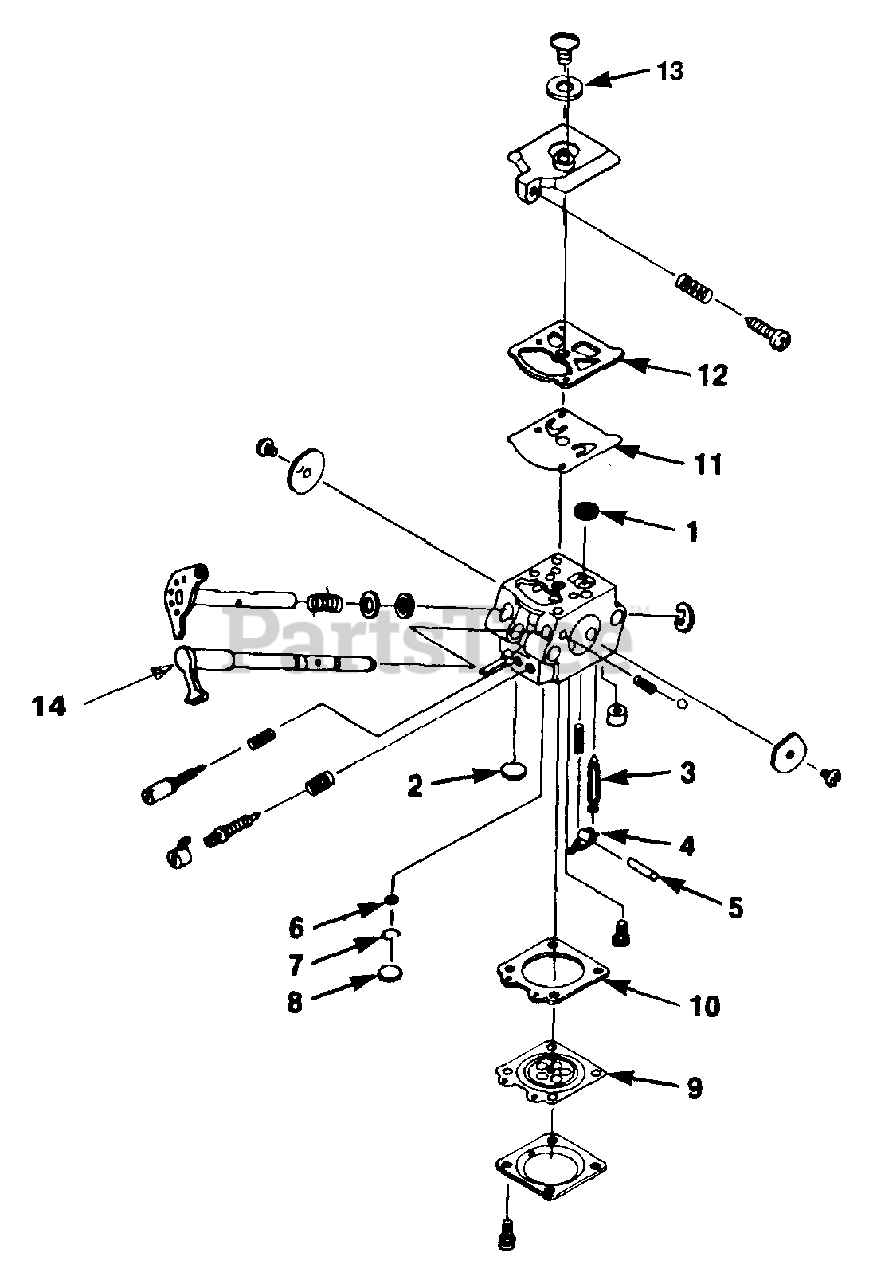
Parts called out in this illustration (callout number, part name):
1	Repair Kit
2	Repair Kit
3	Repair Kit
4	Repair Kit
5	Repair Kit
6	Repair Kit
7	Repair Kit
8	Repair Kit
9	Gasket/Diaphragm Kit
9	Repair Kit
10	Gasket/Diaphragm Kit
10	Repair Kit
11	Gasket/Diaphragm Kit
11	Repair Kit
12	Gasket/Diaphragm Kit
12	Repair Kit
13	Gasket/Diaphragm Kit
13	Repair Kit
14	Choke Lever and Rod
